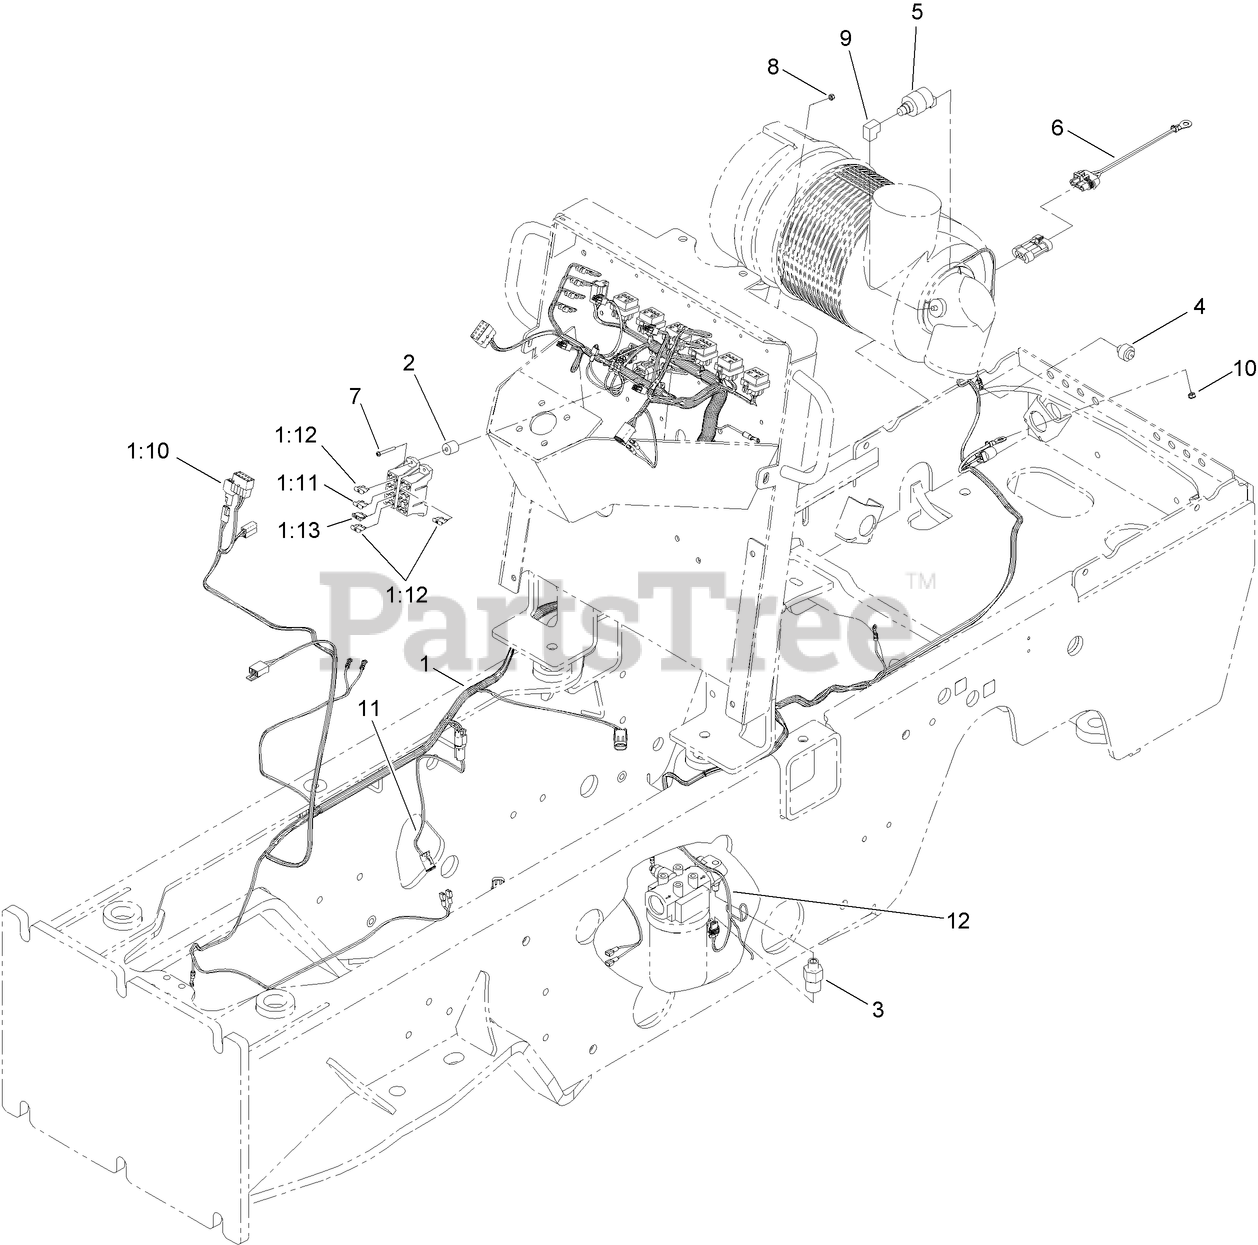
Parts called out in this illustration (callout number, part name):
1	WIRE HARNESS ASM
1:11	FUSE-2 AMP
1:12	FUSE-BLADE, 10 AMP
1:13	FUSE-BLADE, 15 AMP
2	SPACER
3	SWITCH-PRESSURE
4	SENDER-WATER TEMP
5	SWITCH ASM
6	HARNESS-WIRE, FUSIBLE LINK
7	SCREW-PPH
8	NUT-LOCK
9	FITTING-ELBOW, 90
10	NUT-HEX
11	HARNESS-WIRE (HYD DRIVE EXTENSION)
12	HARNESS-WIRE (HYD TEMP EXTENSION)
